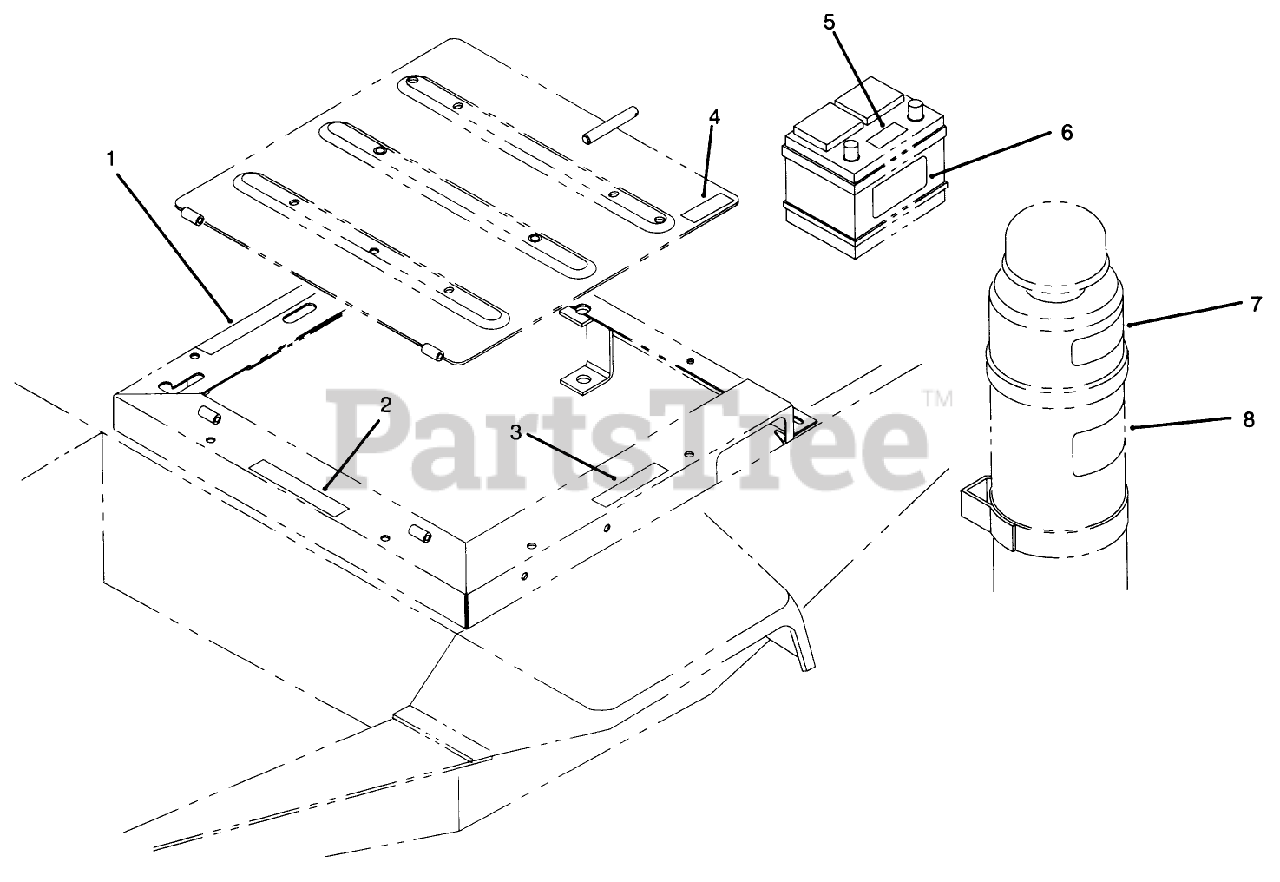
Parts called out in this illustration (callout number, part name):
1	DECAL-THROTTLE AND LIFT CONTROL
2	DECAL-STARTING INSTRUCT.
3	DECAL-WARNING
4	DECAL-DIESEL
5	DECAL-DANGER
6	DECAL-BATTERY
7	DECAL-FLUID, STARTING
8	DECAL-BLANK
